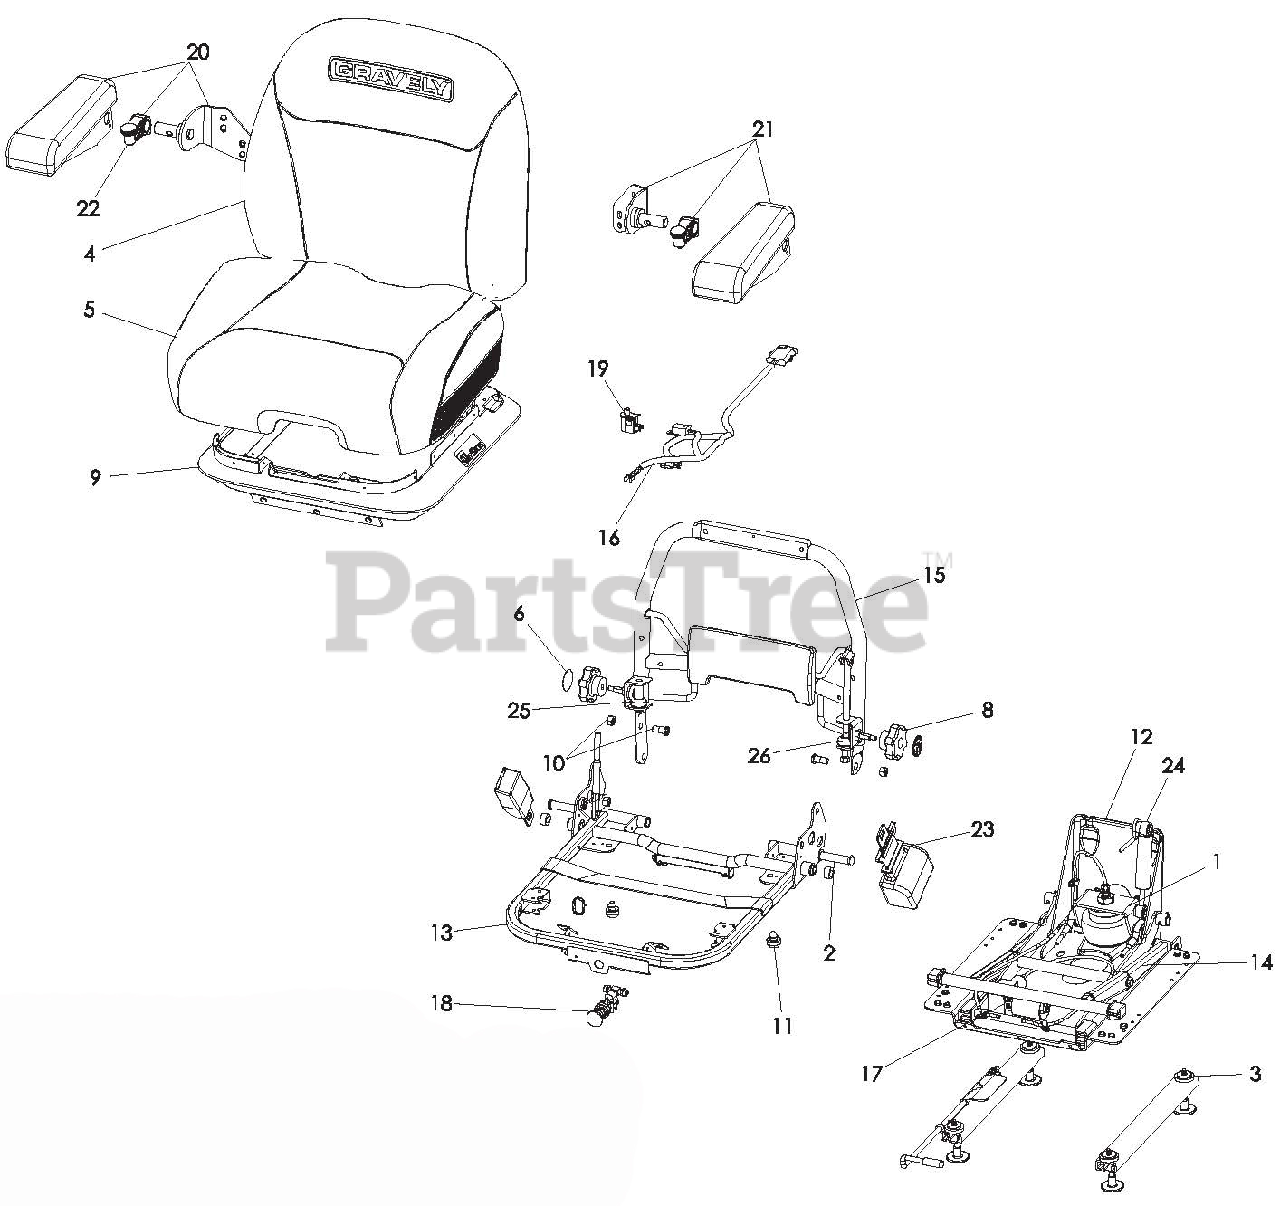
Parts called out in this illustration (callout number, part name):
1	KIT, SPRING AND SADDLE
2	KIT, SHAFT/BEARING
3	KIT, SLIDE
4	KIT, BACK CUSHION
5	KIT, SEAT CUSHION
6	KIT, LABEL
7	KIT, BACK PANEL
8	KIT, KNOB
9	KIT, BOOT
10	KIT, PIVOT BOLT
11	KIT, BUMPER
12	KIT, SUSPENSION BASE WELDMENT
13	KIT, SEAT FRAME WELDMENT
14	KIT, LINKAGE ASSEMBLY
15	KIT, BACK FRAME WELDMENT
16	KIT, WIRE HARNESS
17	KIT, COMPRESSOR
18	KIT, AIR VALVE
19	KIT, OPS SWITCH
20	KIT, RH ARMREST ASSEMBLY
21	KIT, LH ARMREST ASSEMBLY
22	KIT, ARMREST STOP
24	KIT, SHOCK ABSORBER
25	KIT, GEAR
26	KIT, GEAR
